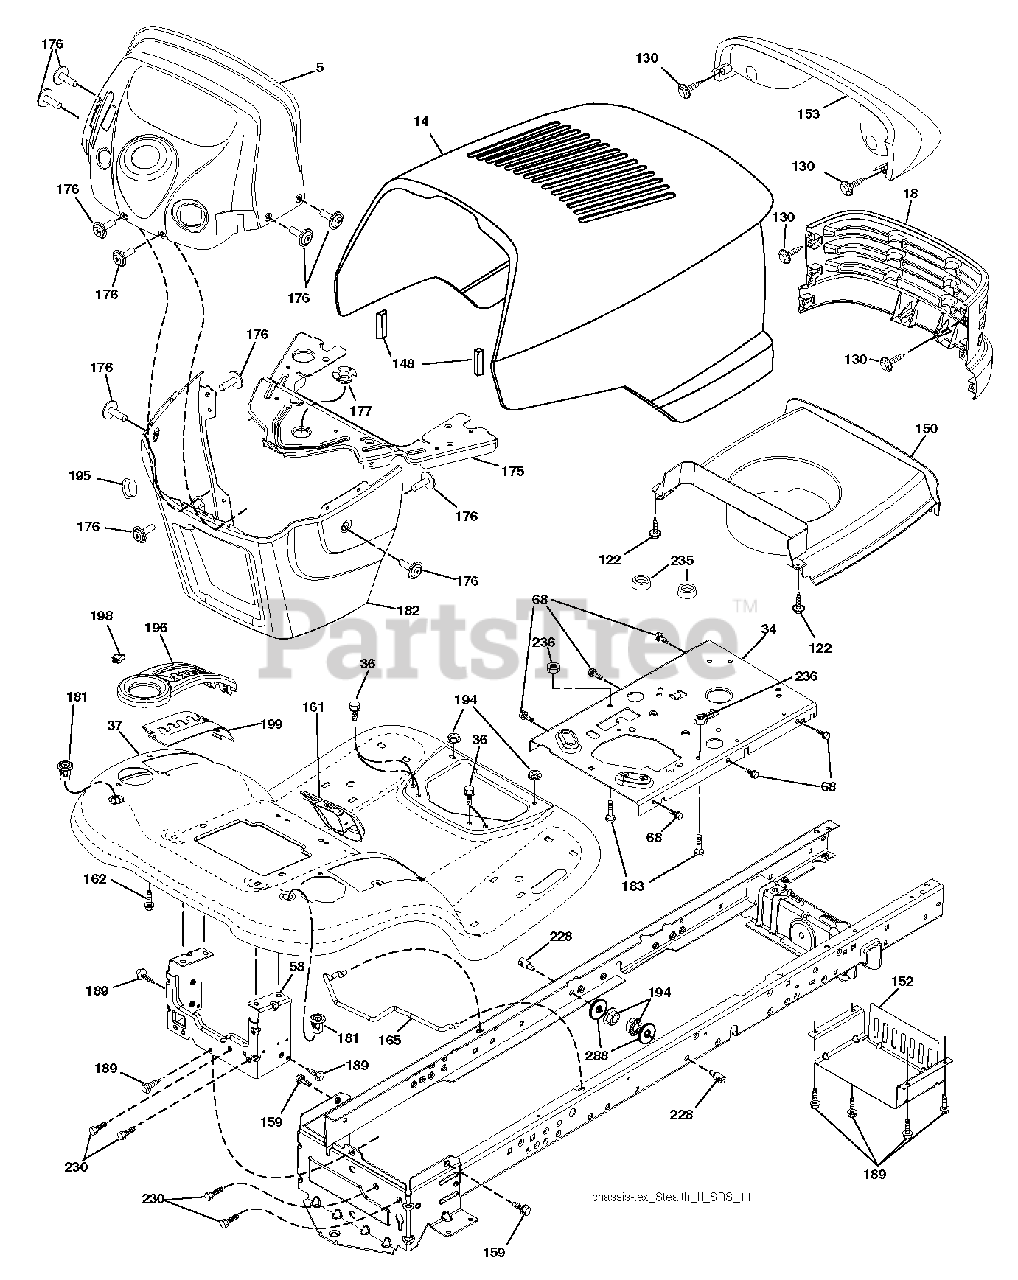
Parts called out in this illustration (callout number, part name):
5	DASH.UPR.STEALTH
34	PLATE.ENGINE.WELDED.CHASSIS
36	SCREW 5/16"
58	DRAWBAR.UPPER.2PC,LRG.FENDER
68	SCREW LT
122	SCREW.WSHD.HEX10-32X5/8
130	SCREW
148	EXTRUSION BUMPER
150	DUCT HOOD
152	SHIELD BROWNING
159	SCREW, 3/8-16X3/4
161	CONSOLE.FUEL.WINDOW.STGT.BLACK
162	SCREW.HI-LO.CONSOLE
165	SUPPORT.TANK.REAR.W/TE
175	CROSSMEMBER.
176	SCREW.#10-24X5/8.RN.QU
177	BUSHING,STEERING
181	FEND/FTRST.PCH.CPH.NFW
182	DASH.LOWER.
183	BOLT.5/16-18X1-1/4 FULL.THREAD
189	SCREW
194	NUT LOCK HEX FLANGE 5/16-18
195	PLUG.HOLE.DASH.LOWER.12V.BLK
198	INDICATOR DECK LIFT
199	PLATE DECK LIFT
228	STUD.FASTNER.W/ANTI-ROTATE
230	SHOULDER BOLT 5/16-18TT
235	SPACER FENDER
236	NUT.CENTERLOCK.5/16-
288	WASHER
